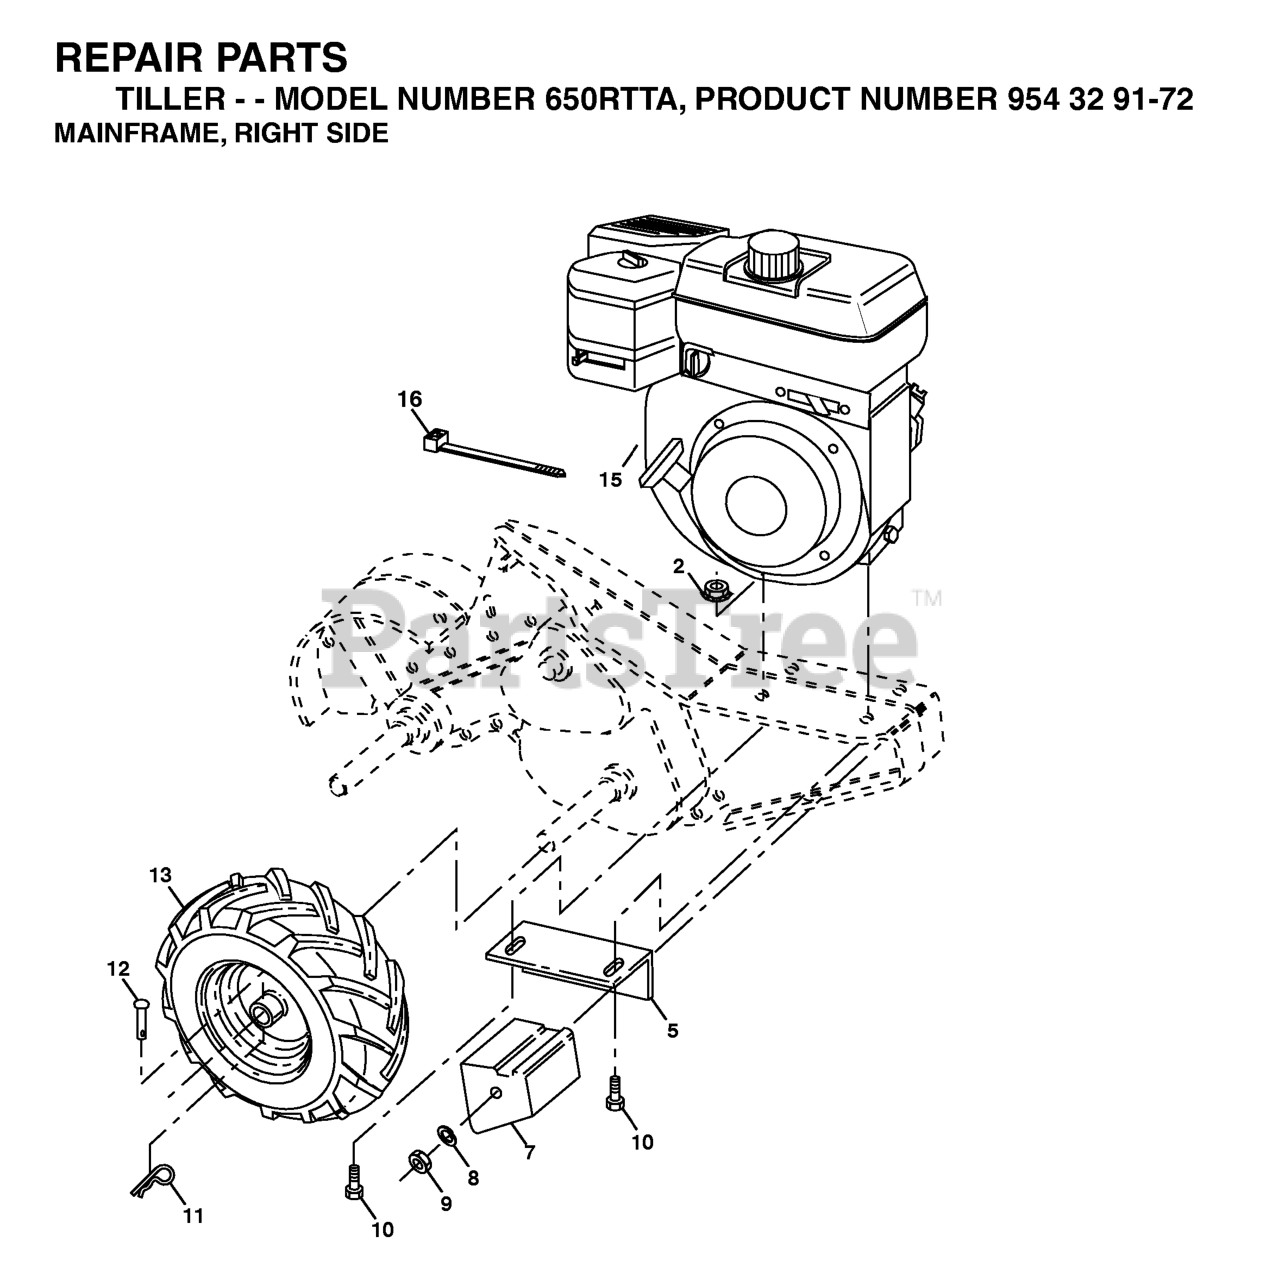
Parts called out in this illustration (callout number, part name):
2	LOCKNUT-FLANGE 5/16-18
5	DNO BRACKET RH CRT
7	COUNTERWEIGHT, RH
8	WASHER, LOCK 3/8
9	NUT.HEX.3/8-16UNC
10	BOLT
11	RETAINER M
12	RIVET,DRILLED
13	TIRE.16X4-8.CHEVRON.TILLER
16	TIE GUIDE
